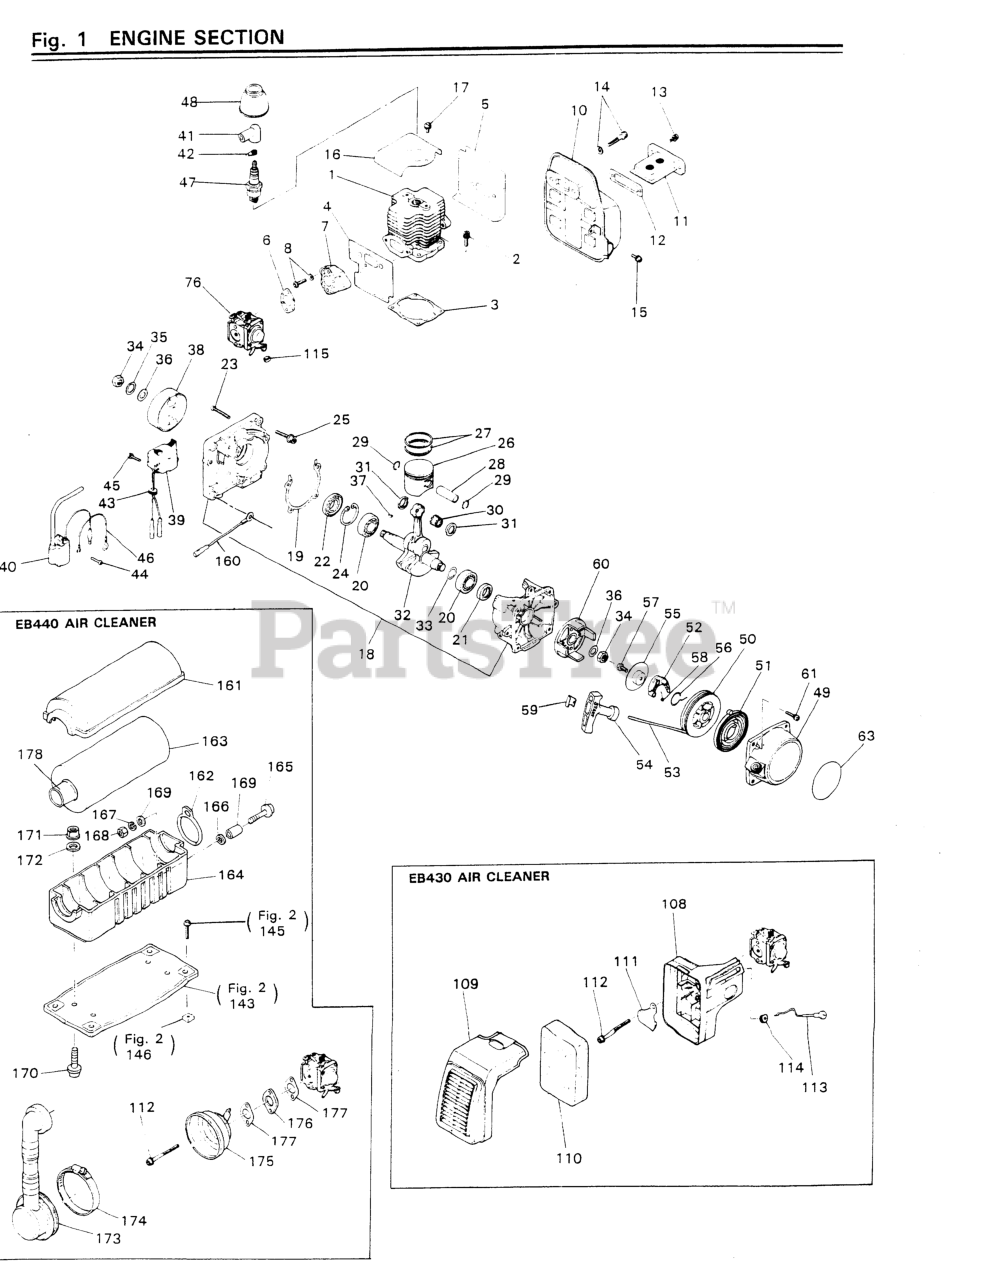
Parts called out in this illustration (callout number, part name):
8	BOLT, M5 X 25 (RPLS.1491-14120
11	ARRESTER
13	SCREW, M4 x 10
15	SCREW, M5 x 12
17	SCREW, M5 x 12
21	SEAL, OIL - STARTER SIDE
23	SCREW, M5 x 30(RPLS 0263-00530
24	RING, SNAP, M35 X 1.5
27	RING, PISTON (RPLS -41210)
28	PIN, PISTON
29	RING, SNAP
30	BEARING
31	WASHER (RPLS 1491-41510)
33	SHIM (REPLACES 848-870-G000)
35	WASHER, M10 X 25
36	WASHER, M10 x 1.6
37	KEY
40	COIL, IGNITION
42	SPRING
43	GROMMET
44	SCREW, M4 x 16
45	SCREW (REPLACES -30414)
46	CABLE COMPLETE
48	CAP (NO LONGER AVAILABLE)
49	RECOIL ASSEMBLY
50	REEL (NLA)
51	SPRING, SPIRAL (NLA)
52	RATCHET
53	ROPE
54	KNOB
55	RETAINER (NLA)
56	SPRING (NLA) (REPLACES -75250)
58	SPRING, DOG (NLA)
60	PULLEY (NLA) (RPLS -75210)
61	SCREW (USE 0263-90520 )
161	COVER, CLEANER
162	BAND
163	ELEMENT
164	CASE, CLEANER
166	WASHER, M5 X .8
167	WASHER, SPRING M4 x 1.3
168	NUT, M5 X 4
169	COLLAR (NLA)
170	SCREW, M5 x 16
171	NUT (B)
172	WASHER, M5 X .8
174	CLAMP
175	CASE, CLEANER
NI	CLEANER, AIR
